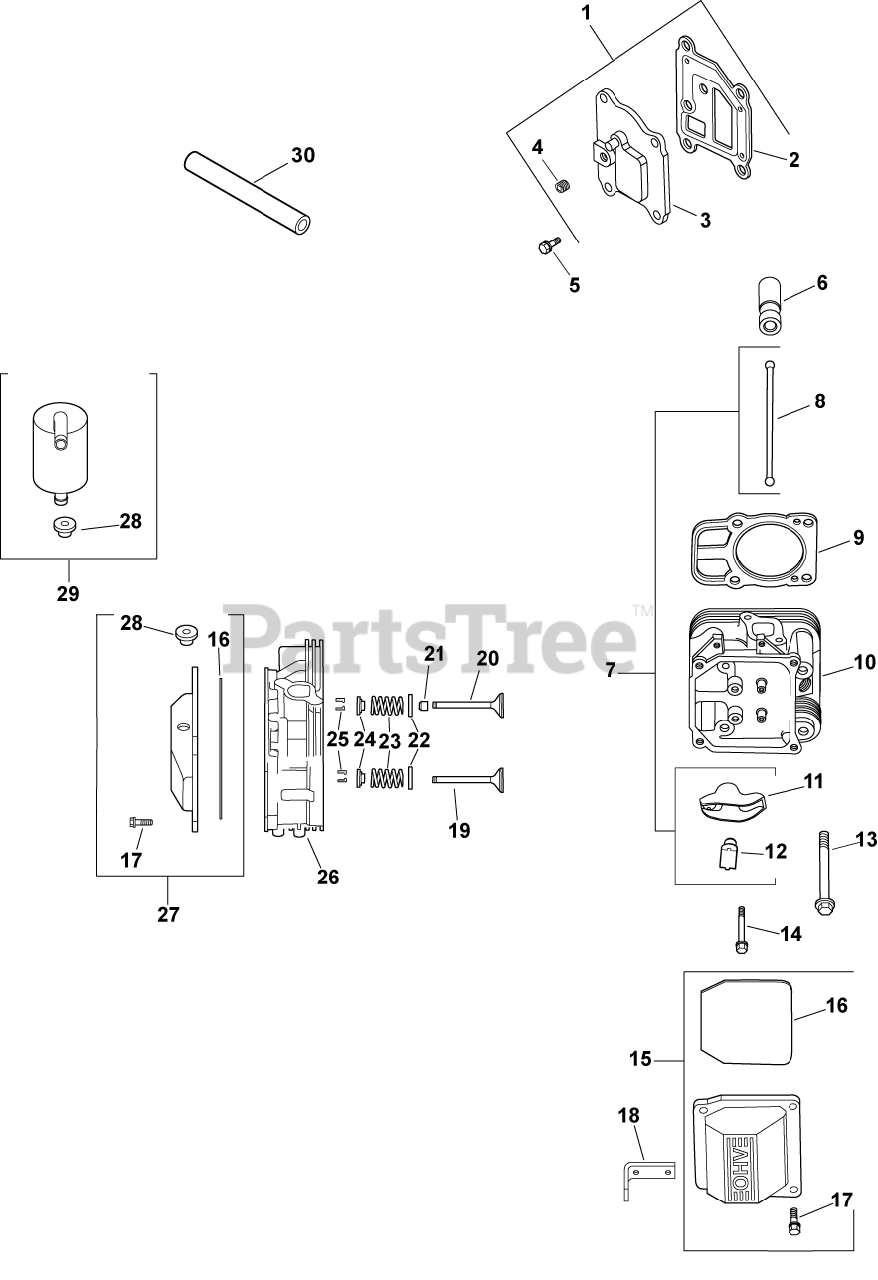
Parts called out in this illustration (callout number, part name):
1	KIT, BREATHER COVER W/GASKET
2	GASKET, BREATHER-USE 24 041 67-S
3	COVER, BREATHER -USE 24 096 125-S
4	PLUG, CTSK PIPE 1/8"
5	SCREW,FLG THD FRM M6X1.0X20-(#25086396S)
6	LIFTER, HYDRAULIC VALVE-USE 25 351 10-S
7	KIT, VALVE TRAIN
8	ROD, PUSH
9	KIT, GSKT CYL HD (C22-23 674CC)
10	HEAD, ASSEM CYLINDER #2 -USE 24 318 113-
11	ARM, ROCKER
12	PIVOT, ROCKER ARM
13	SCREW - USE 62 086 08-S
14	SCREW, ROCKER ARM PIVOT-USE M-640034-S
15	KIT, VALVE COVER-PLAIN
16	O-RING (YELLOW), VALVE COVER
17	SCREW, FLG M6X1.0X30
18	STRAP, LIFTING-USE 25 445 03-S
19	VALVE, EXHAUST (STD) - USE 32 016 01-S
20	VALVE, INTAKE (STD)
21	SEAL, VALVE STEM - (#2503214S)
22	RETAINER, SPRING
23	SPRING, VALVE
24	RETAINER, VALVE SPRING - USE 25 173 28-S
25	KIT, RETAINER
26	HEAD, ASSEM CYLINDER #1 -USE 24 318 105-
27	KIT, VALVE COVER
28	GROMMET, RUBBER
29	KIT, BREATHR SEPARATR-(#24755241S)
30	HOSE, BREATHER
2401602-S	VALVE, EXHAUST (.25)
2401702-S	VALVE, INTAKE (.25)
